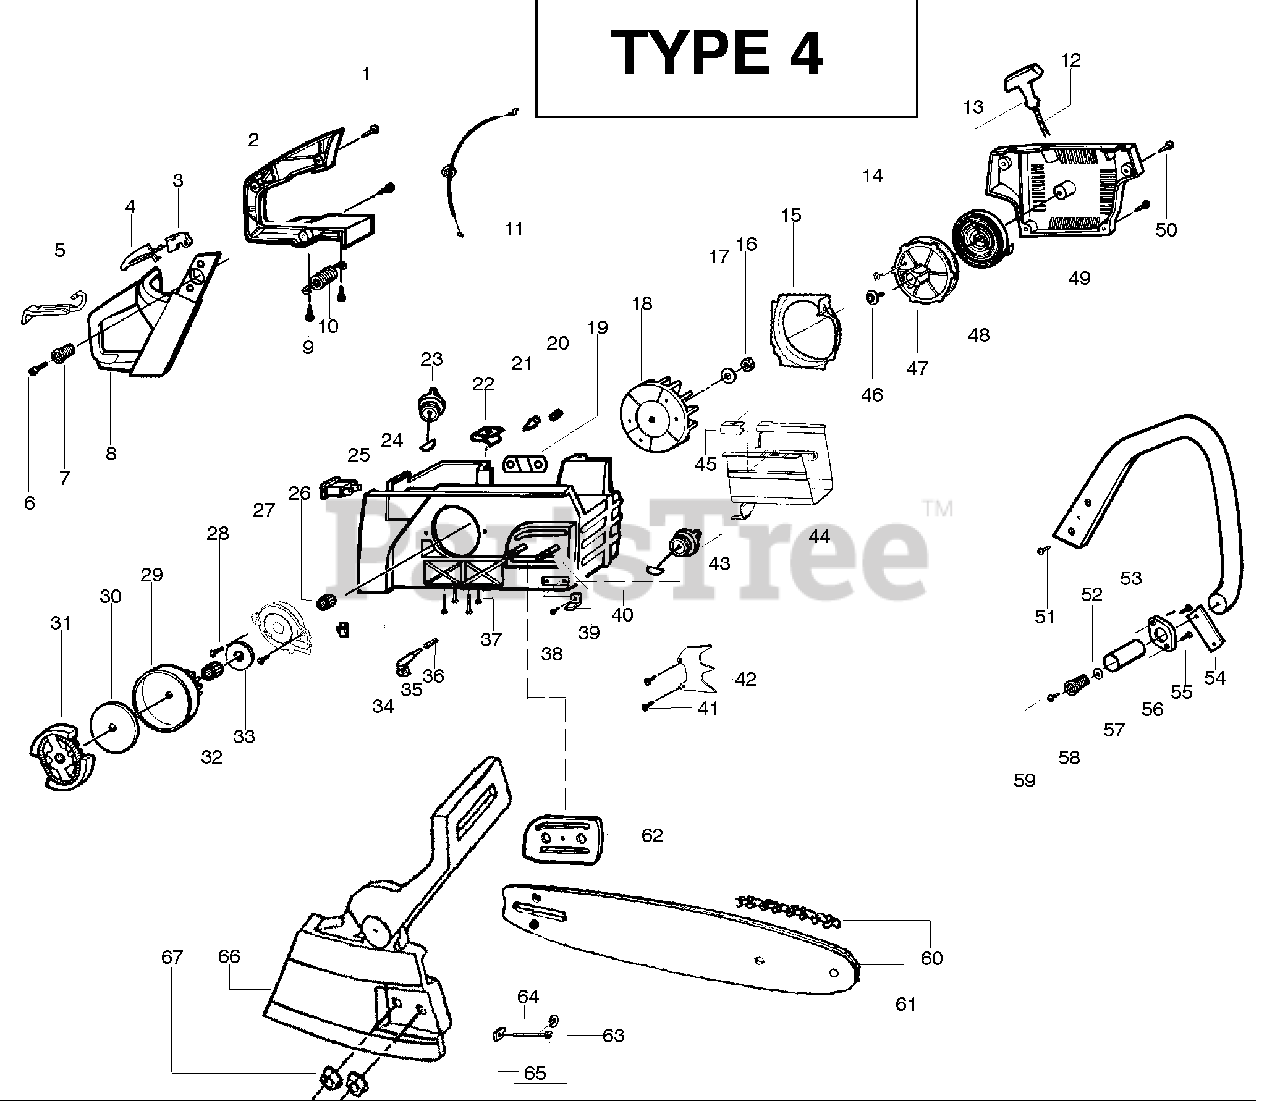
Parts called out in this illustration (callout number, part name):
3	Trigger-Throttle
4	Lockout-Throttle
7	Spring-Isolator
10	Spring-Isolator
11	Assy-Throttle Cable
13	Handle-Starter
15	Plate-Baffle Fan
17	Washer-Flywheel
18	Assy-Flywheel
19	Plate-Support (Bar Stud)
23	Assy-Fuel Cap
26	Worm-Oil Pump
27	Assy-Oil Pump
29	Kit-Clutch Drum
30	Washer-Clutch
32	Bearing-Clutch
33	Washer-Thrust
34	Seal-Oil
36	Filter-Oil
39	Chain Catcher
41	Screw
42	Kit-Spike Assy
43	Assy-Oil Cap
47	Kit-Starter Pulley
48	Spring-Recoil
49	Housing-Fan
53	Handle-Front
54	Front Strap-AV
56	Plate-Isolator
57	Spring Sleeve-AV
58	Spring-Isolator
63	Kit-Bar Adj.
64	Retainer-Bar Adjust
65	Pin-Bar Adjust
66	Assy-ChainBrake
67	Nut-Bar Mounting
